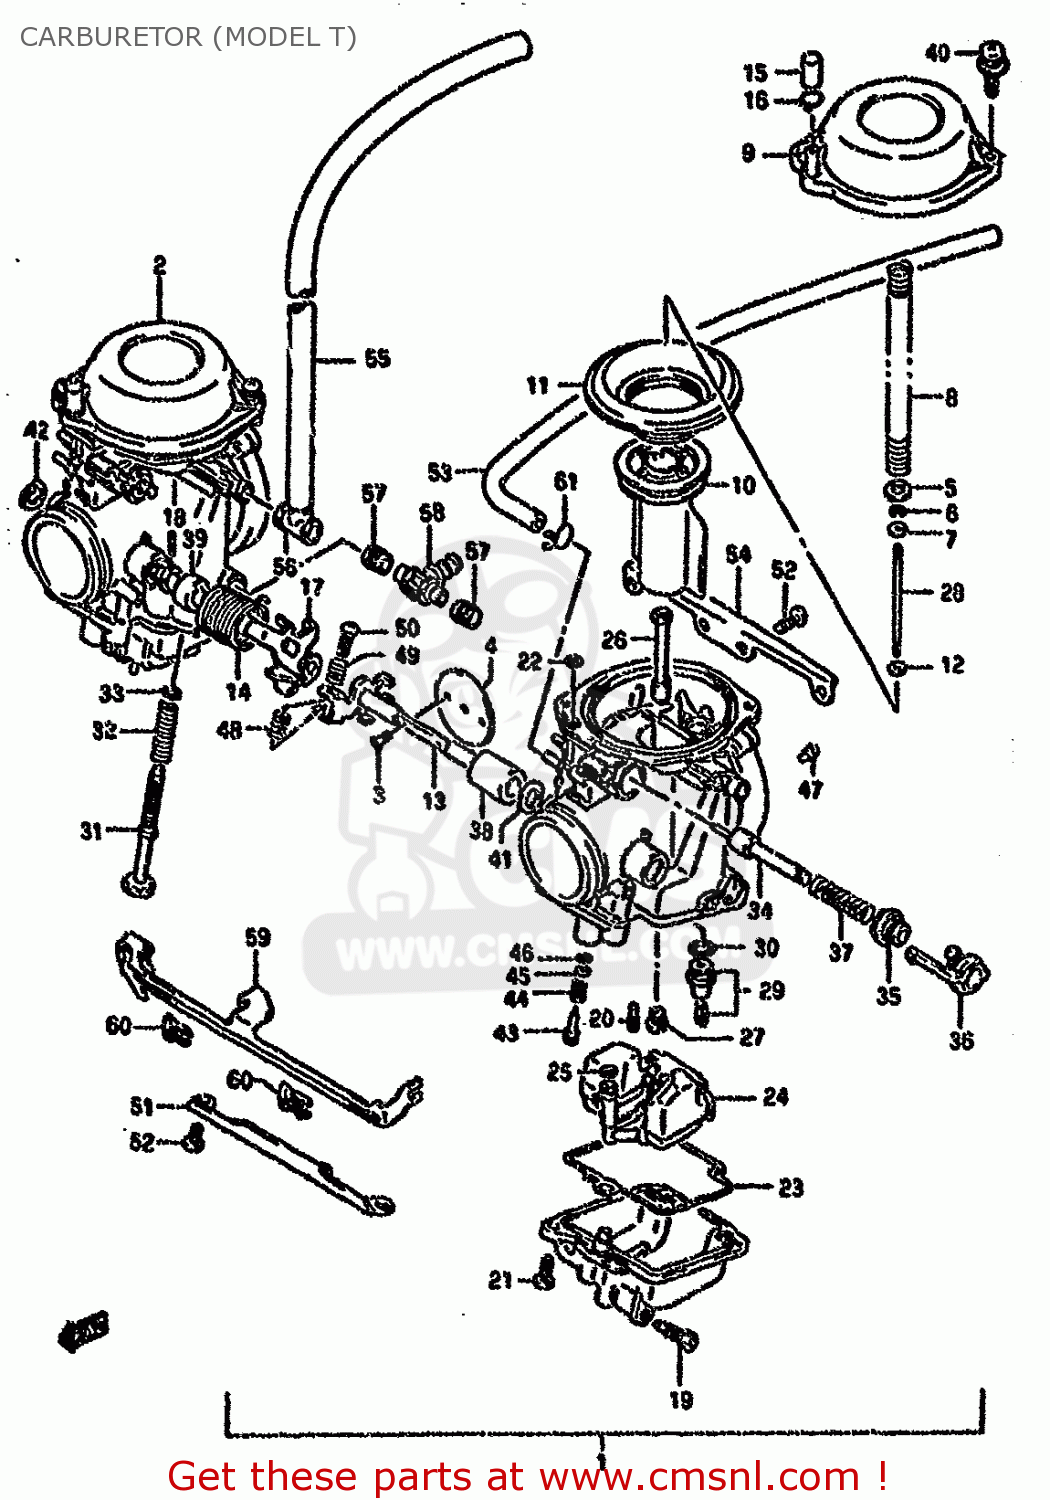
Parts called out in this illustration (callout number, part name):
1	CARBURETOR ASSY, LH
2	CARBURETOR ASSY, RH
3	SCREW
4	VALVE,THROTTLE(120)
5	RING
6	E RING
7	WASHER
8	SPRING
9	COVER,DIAPHRAGM
10	VALVE,PISTON
11	DIAPHRAGM
12	RING
13	SHAFT ASSEMBLY
14	SPRING
15	CAP
16	CLIP
17	SHAFT ASSEMBLY
18	SEAL
19	SCREW,DRAIN
20	JET(40)
21	SCREW
22	O RING
23	GASKET,FLOAT CHAMBER (NAS)
24	FLOAT ASSY
25	O RING
26	JET,NEEDLE(O-2)
27	JET,MAIN(115)
28	NEEDLE,JET
29	VALVE ASSY,NEEDLE
30	O-RING,NEEDLE VALVE
31	SCREW,ADJUSTER
32	SPRING
33	WASHER
34	PLUNGER ASSY
35	CAP,STARTER
36	HOLDER,GUIDE
37	SPRING
38	RING
39	RING
40	SCREW
41	GASKET,THROTTLE SHAFT (NAS)
42	E RING
43	SCREW,PILOT
44	SPRING
45	WASHER
46	O RING,PILOT AIR SCREW
47	JET,AIR
48	SPRING,THROTTLE SCREW
49	SPRING
50	SCREW
51	PLATE
52	SCREW
53	HOSE(5X9X350)
54	PLATE
55	HOSE(7X11X600)
56	HOSE
57	SEAL
58	NIPPLE
59	LEVER
60	HOLDER
61	CLIP
